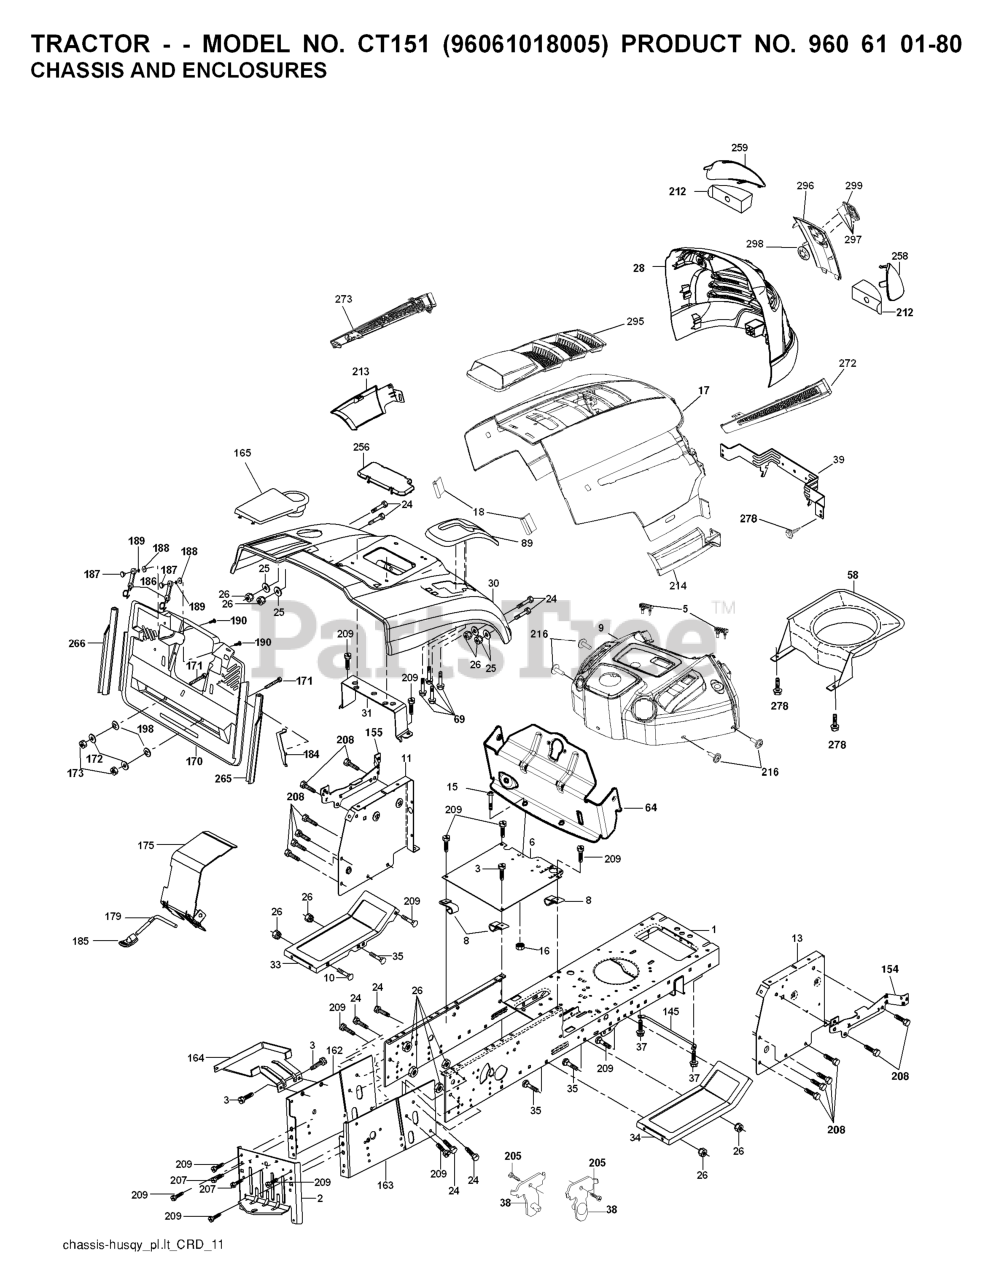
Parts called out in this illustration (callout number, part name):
2	DRAWBAR
3	SCREW 3/8-16X3/4
5	BUMPER DASH
6	PLATE
8	CLIP,INSULATOR
10	BOLT D
11	PANEL.DASH.LH.LTX
13	PANEL ASM, DASH RH
15	Screw, Machine, Truss Head 5/16-18 UNC x 3/4
16	NUT
17	HOOD
18	BUMPER.HOOD.TEX.HUSQVARNA
25	WASHER
26	NUT
28	RP GRILLE/LENS ASM.
31	BRACKET SUPPORT FENDER
33	FOOTREST PNT LH
34	FOOTREST PNT RH
37	Screw 5/16-18 x 1/2 Hex, Self Tapping 5/16-18 x 1/2
38	BRACKET ASM PIVOT MOWER REAR
39	BRACKET PIVOT
69	SCREW.HI-LO.CONSOLE
145	ROD.PIVOT.HOOD
162	BRACKET
163	BRACKET EXTEN CHASSIS RH CRD
165	RP.COVER.BATTERY.CRD.GREY
172	WASHER
175	DOOR TRAP
179	ROD PIVOT FBI
184	BRACKET.ACTUATOR.BAGGER.SRD
186	LATCH ASSY
187	WELDNUT
189	LOCKWASHER #10
190	SCREW
207	SCREW, 5/16-18 X 1/2
208	SCREW 3/8-16X1/2
209	SCREW, 3/8-16X3/4
212	INSERT REFLECTIVE
213	SKIRT SIDE LH
214	SKIRT SIDE RH
216	SCREW HEXWSHR 1/4-20X3/4
256	COVER FENDER CRD
258	LENS.HUSQVARNA LT.RH
259	LENS.HUSQVARNA LT.LH
265	SEALING
266	SEALING
272	VENT SIDE HOOD RH
273	VENT SIDE HOOD LH
278	SCREW
295	VENT TOP HOOD
296	TRIM
297	CLIP.RETAINER.TINNER.
298	NUT PUSH M
299	RP LOGO
